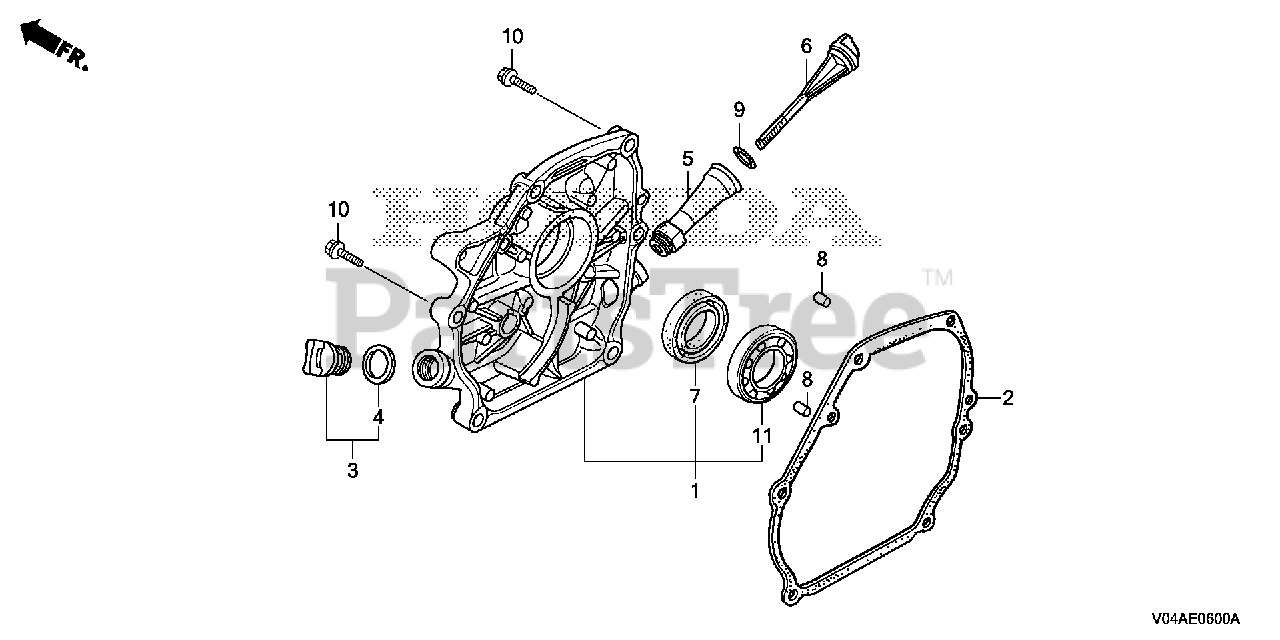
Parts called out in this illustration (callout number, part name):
1	COVER ASSY., CRANKCASE
2	GASKET, CASE COVER (NON-ASBESTOS)
3	CAP ASSY., OIL FILLER (BLACK)
4	GASKET, OIL FILLER CAP
5	PIPE, OIL FILLER
6	DIPSTICK, OIL
7	OIL SEAL (25X41X6) (NOK)
8	PIN, DOWEL (8X14)
9	O-RING (23X2.8)
10	BOLT, FLANGE (8X32)
11	BEARING, RADIAL BALL (6205)
